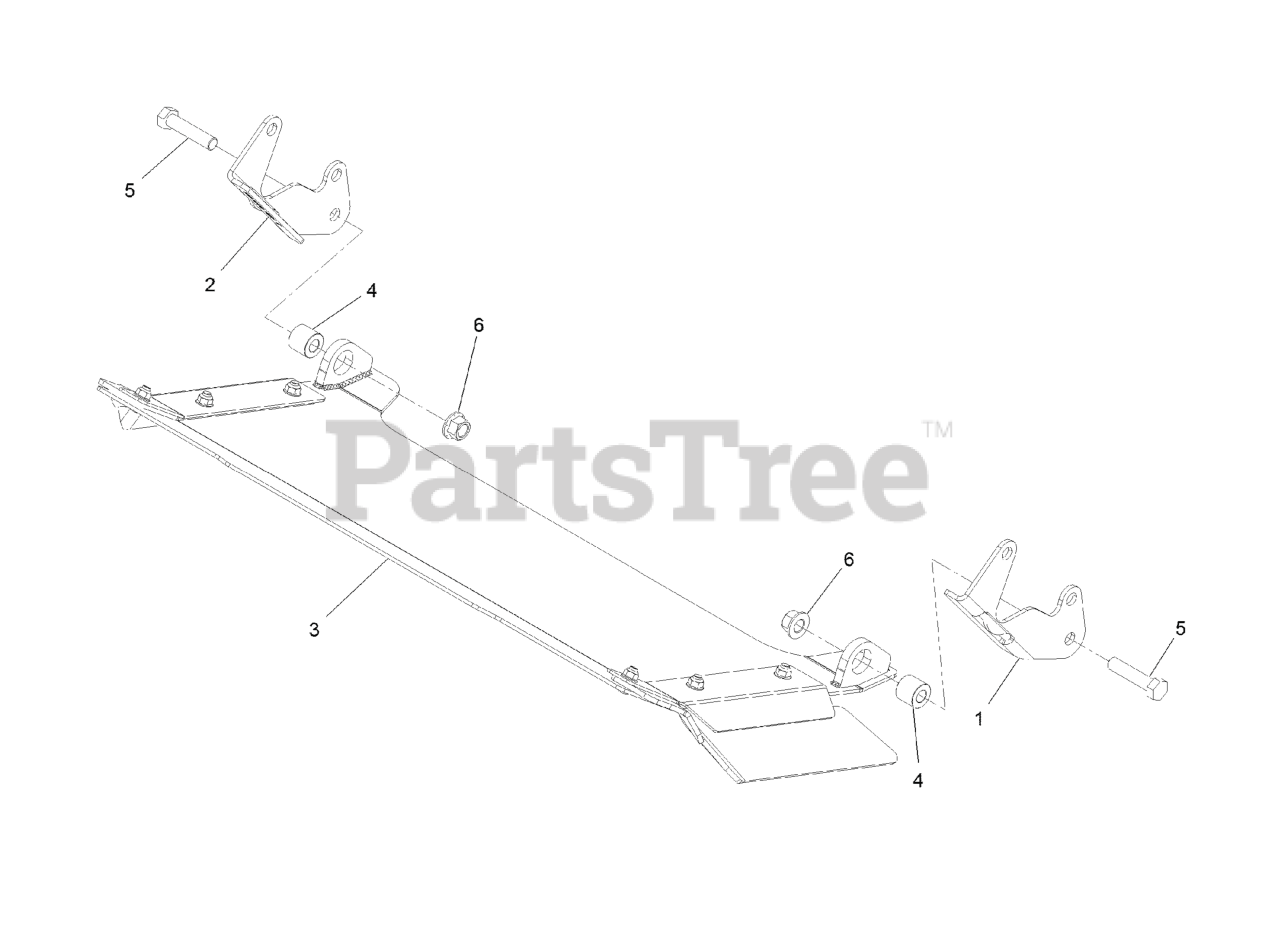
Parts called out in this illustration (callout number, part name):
1	BRACKET-DISCHARGE MOUNT,
2	BRACKET-DISCHARGE MOUNT,
3	DISCHARGE TUNNEL ASM
4	BUSHING-SLEEVE
5	SCREW-HH
6	Nut-Lock 1/2-13
